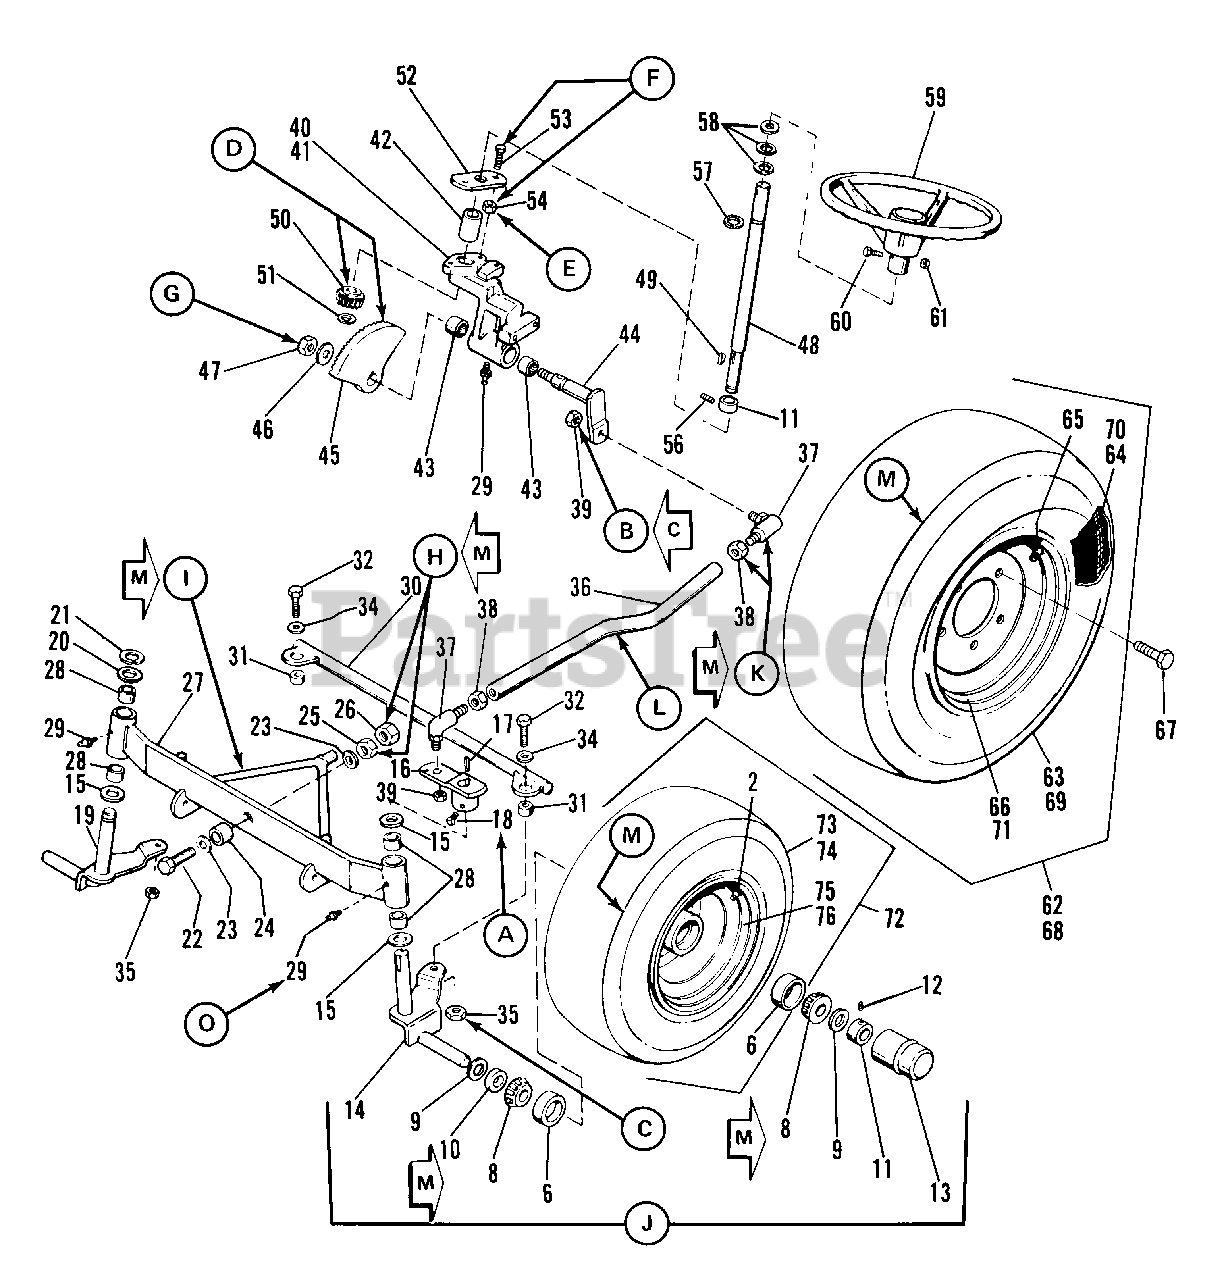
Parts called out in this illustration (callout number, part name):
2	VALVE STEM & CAP (7010 Only)
6	CUP, Bearing (7010 Only)
8	CONE, Bearing
11	COLLAR, Set
12	SETSCREW, Sq. Hd., Cup Pt., 5/16-18 x 5/16
13	CAP, Hub
14	SPINDLE ASSY, L.H.
16	ARM, Steering, L.H.
17	KEY, Square
18	SETSCREW, 5/16-18 x 1/2
19	SPINDLE ASSY, R.H.
21	RING, Retaining, No. 75
22	CAPSCREW, Hex Hd., 1/2-13 x 2-1/4
23	WASHER, Plain, 1/2
25	LOCKNUT, Hex, 1/2-13
26	NUT, Jam Hex, 1/2-13
27	FRONT AXLE ASSY
29	FITTING, Grease
30	TIE ROD ASSY
32	CAPSCREW, Hex Hd., 3/8-16 x 1-1/4
33	LOCKWASHER, 3/8
34	WASHER, Plain, 3/8
35	NUT, Hex, 3/8-16
36	LINK, Drag
37	JOINT, Ball
38	NUT, Jam Hex, 1/2-20
39	LOCKNUT, Hex, 1/2-20
40	STEERING HOUSING ASSEMBLY
41	HOUSING, Steering
43	BEARING, Needle
44	STEERING ARM ASSEMBLY
45	GEAR, Bevel
46	WASHER, Plain, 7/16
47	LOCKNUT, Hex, 7/16-14
48	SHAFT, Steering
49	KEY, Woodruff, No. 6, 5/32 x 5/8
50	PINION, Bevel
51	"E" RING
52	PLATE, Steering
53	CAPSCREW, Hex Hd., 3/8-16 x 1-1/4
54	LOCKNUT, 3/8-16
56	SETSCREW, Sq. Hd., 5/16-18 x 1/4
57	RING, Retaining
59	WHEEL, Steering
60	CAPSCREW, Hex Hd., 5/16-18 x 1-1/4
61	LOCKNUT, Flange, 5/16-18
62	WHEEL & TIRE ASSY., 23 x 8.50-12
63	TIRE 23-8.50 x 12
64	TUBE, 23 x 8.50-12
65	STEM & VALVE CAP
66	WHEEL, Drive
68	WHEEL & TIRE ASSEMBLY 23-10.50 x 12 (7016 Only)
69	TIRE, 23 x 10.50-12 Carlisle
69	TIRE, 23 x 10.50-12 Goodyear
69	TIRE, 23 x 10.50-12 (Firestone)
70	TUBE, 23 x 10.50-12
71	WHEEL DRtVE
72	WHEEL & TIRE ASSY., 16 x 6.50-8
73	TIRE, 16 x 6.50-8 Goodyear
73	TIRE, 16 x 6.50-8 Carlisle
75	WHEEL ASSY
